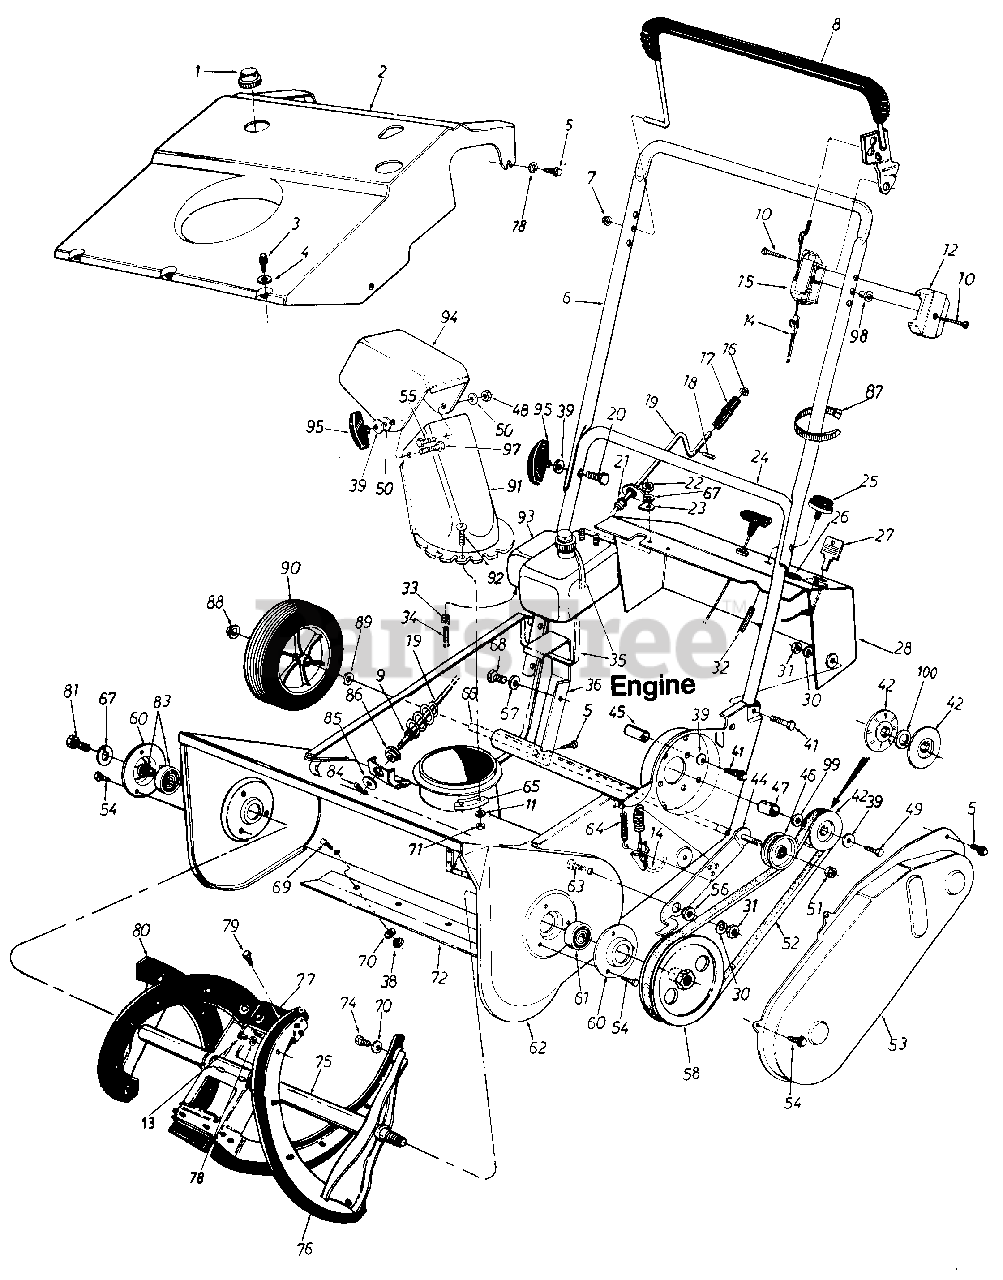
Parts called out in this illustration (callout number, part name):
1	Gas Tank Cap
2	21" Shroud
3	Hex B-Tap Scr. #10 x .38"
4	Spr.-Wash. .206" I.D. x .448"
5	Hex L-Wash. Hd. AB-Tap 1/4 x.62" Lg.
7	Cap Speed Nut
8	Control Handle Ass'y.-L.H.
9	Fl-Wash. .385" I.D. x .62"
10	Truss Mach. Hi-B 0 Tap Scr. #12 x 1.5" Lg.
11	Fl-Wash. .281" I.D. x .5" O.D.
12	Control Panel Half
13	POP Rivet .188" Dia.
14	Clutch Cable 35" Lg.
15	Control Panel Half
16	Push Cap 3/8" Rod
17	Knob-3/8" Dia. Hole
18	Roll Pin 1/8" Dia. x .63" Lg.
19	Chute Crank Ass'y.
20	Curved Carriage Bolt 5/16-18 0 x 1.75" Lg.
21	Chute Crank Grommet
22	Hex Nut 1/4-20 Thd.
23	Upper Chute Crank Brkt.
24	Lower Handle (Painted)
24	Lower Handle (Chrome)
26	Plastic Plug
27	Plastic Key
28	Dash Panel Ass'y.
30	L-Wash. 5/16" I.D.
31	Hex Nut 5/16-18 Thd.
32	Primer Hose-11" Lg.
33	Hose Clamp-.406" Dia.
34	Gas Line-9" Lg.
35	Cable Tie-17.75" Lg.
36	Engine Support Brkt.
38	Hex Jam Nut 1/4-20 Thd.
39	Bell-Wash. .345" I.D. x .88"
41	Hex Bolt 5/16-18 x 1.5" Lg.
42	3/8" "V"-Pulley Half .625" I.D. x 6.0" O.D.
44	Idler Brake Brkt. Ass'y.
45	Spacer .325" I.D. x .625" O.D. x .875"
46	Fl-ldler w/Flanges 2.12" O.D.
47	Spacer .635" I.D. x .89" O.D. x .57"
48	Hex L-Nut 5/16-18 Thd.
49	Hex Bolt 5/16-24 x .75" Lg.
50	Fl-Wash. 344n l.D. x 1.25"
51	Hex Patch L-Nut 3/8-24 Thd.
52	V-Belt
54	Hex B-Tap Scr. 1/4" x .38" Lg.
55	Carriage Bolt 5/16-18 x .75"
56	Shld. Spacer .50" Dia. x .27"
58	1/2" "V"-Pulley 1/2-20 L.H. x 6"
60	Bearing Cup
61	Ball Brg. .669" I.D. x 1.574"
64	Extension Spring 1.12" Lg.
65	Chute Flange Keeper
66	Wheel Axle Tubing
67	L-Wash. 1/4" I.D.
68	Hex Wash. S-Tap Scr. 1/4-20 0 x.50" Lg.
69	Carriage Bolt 1/4-20 x .50"
70	Fl-Wash. .281" I.D. x .73"
71	Hex L-Nut 1/4-20 Thd.
72	Shave Plate
74	Hex Wash. B-Tap Scr. 1/4 x .62"
75	Auger Ass'y. 21 "
76	Rubber Spiral-L.H.
77	Rubber Paddle
78	Fl-Wash. .218" I.D. x .62n
79	Hex Wash. B-Tap Scr. #10 x .62" Lg.
80	Rubber Spiral-R.H.
81	Hex Wash. TT-Tap Cl-Scr. 1/4-20 x .75" Lg.
83	Kit-Bearing and Collar
84	Cotter Pin 3/32" Dia. x .75"
85	Fl-Wash. .406" I.D. x 1.25"
86	Hex Bushing .385" I.D.
87	Cable Tie
88	Push Cap 1/2" Dia.
89	Fl-Wash. .510" I.D. x .75"
90	Wheel & Tire Ass'y. 6" x 1.5"
90	Wheel & Tire Ass'y. 7" x 1.5"
91	Lower Chute
92	Truss Mach. Scr. 1/4-20 x .75"
93	Fuel Tank-Two Qt.
94	Upper Chute
95	Knob Handle Ass'y.
97	Carriage Bolt 5/16-18 x 1 "
98	Control Disc Pin
99	Fl-Wash. .635" I.D. x 1.04" O.D.
100	Fl-Wash. .635" I.D. x .93" O.D.
